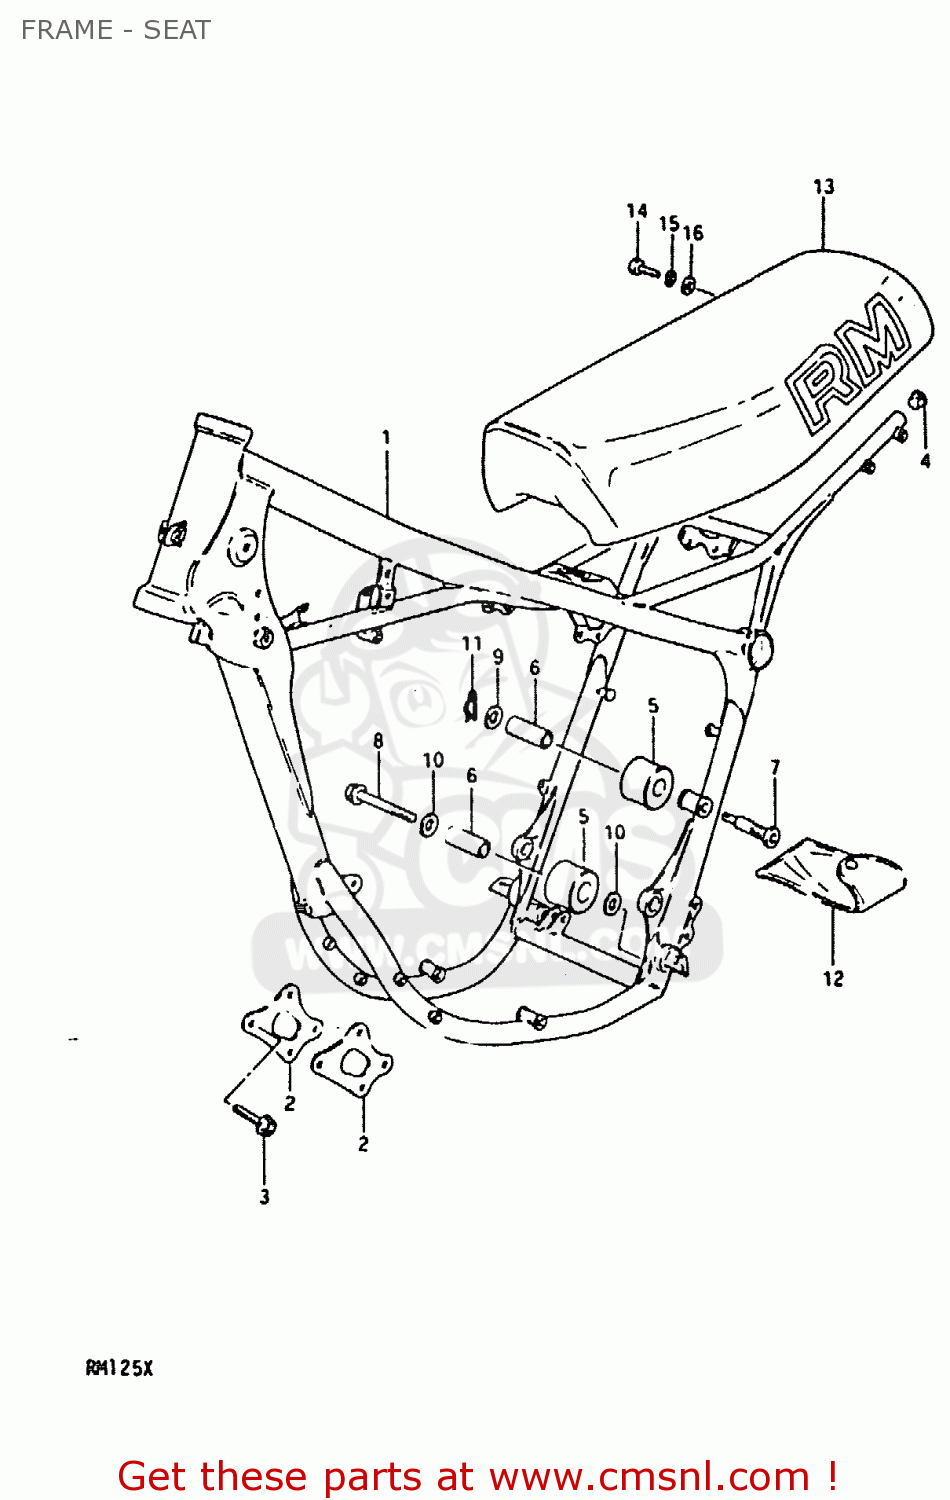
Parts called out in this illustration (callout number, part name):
1	FRAME
2	PLATE,ENGINE MOUNTING
3	BOLT
4	PLUG(OD:17)
5	ROLLER,CHAIN LENGTH CONTROL
6	SPACER,CHAIN LENGTH ROLLER
7	BOLT,CHAIN LENGTH ROLLER
8	BOLT(8X45)
9	WASHER
10	WASHER
11	CLIP
12	13
13	SEAT ASSEMBLY
14	BOLT
15	LOCK WASHER
16	WASHER (8.2X20X1.6)
